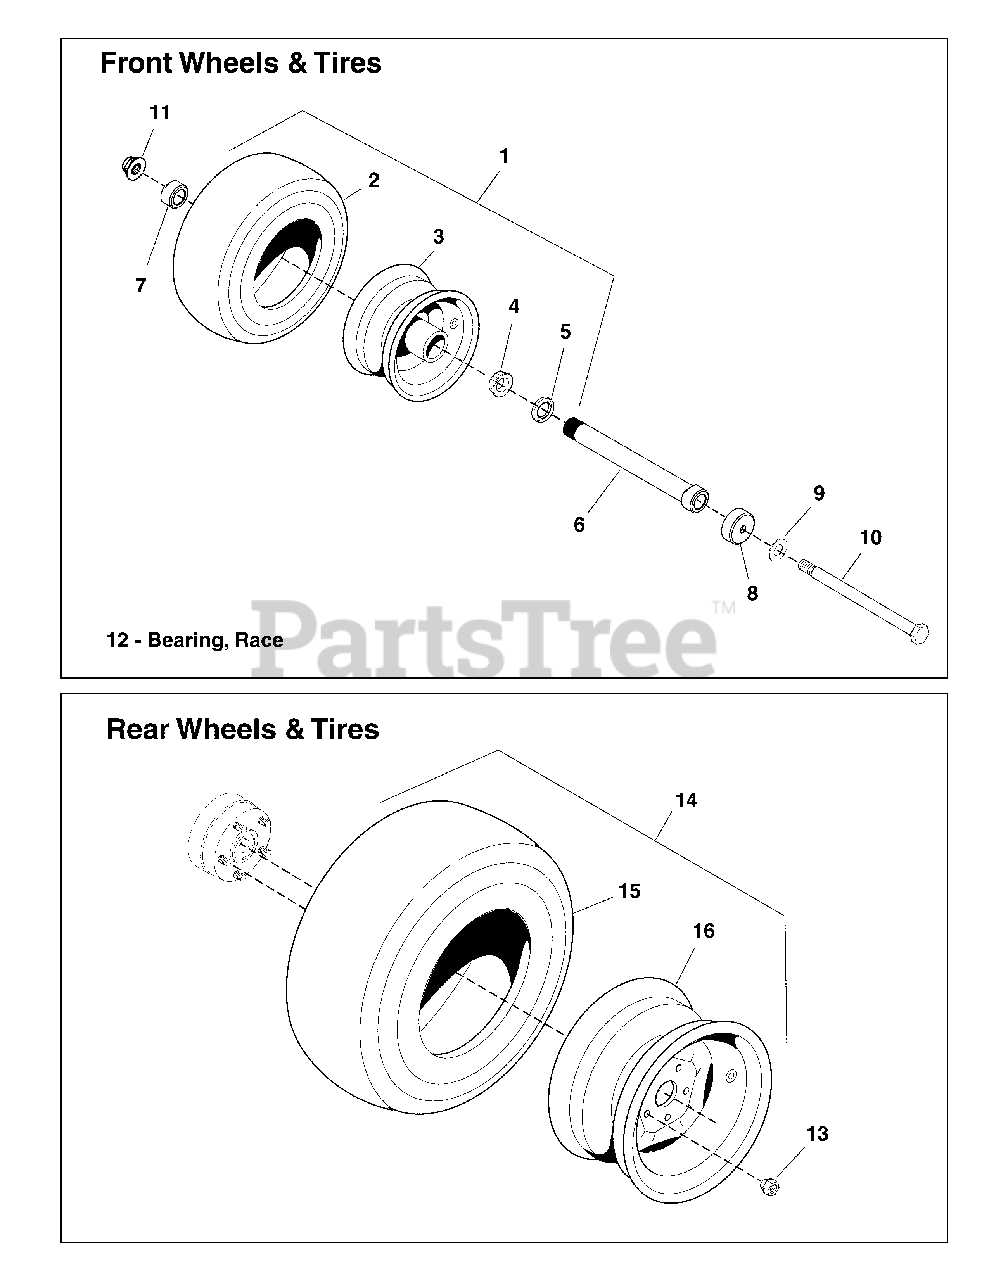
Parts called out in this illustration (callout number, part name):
1	TIRE ASSY, 13 X 6.5 SILVER
2	TIRE, FRONT, 13 X 6.5 X 6 (SV)
3	WHEEL ASSEMBLY, FOR 13 X 6.5 X 6 TIRES (INCLUDES BEARING AND SEALS)
4	BEARING, TAPERED ROLLER (SV)
5	SEAL, GREASE
6	BEARING ADJUSTER, SPACER, 7.062 LG
7	NUT, BEARING ADJUSTER, AXLE
8	DEBRIS, COVER, CASTER WHEELS
9	WASHER, 1/2 SAE
10	BOLT, 1/2-13 X 9 GD5 YZ
11	NUT, 1/2-13 HEX NYLOCK FLANGE
13	NUT, 1/2-20, FOR WHEEL BOLT SILVER
14	TIRE/WHEEL ASM, 24X12.00-12, TURF SMART
15	TIRE, 24X12.00-12, TURF SMART
16	WHEEL, 12 X 8.5
